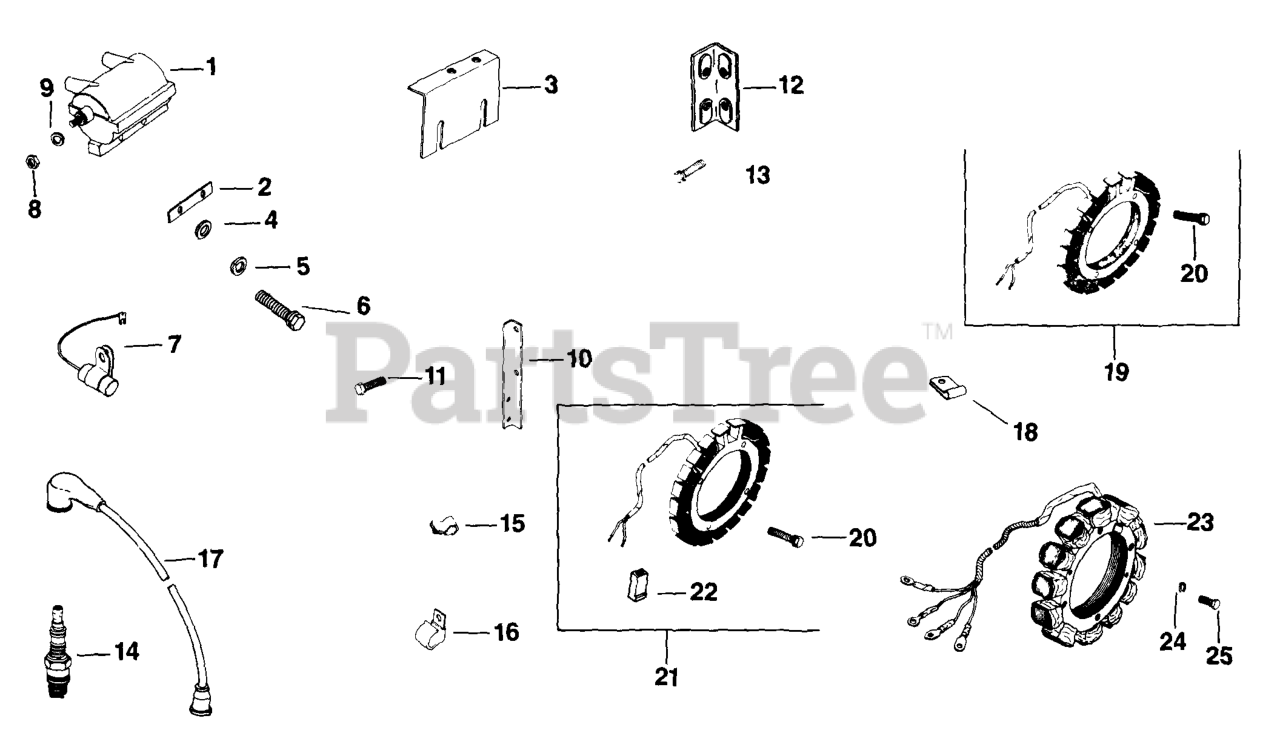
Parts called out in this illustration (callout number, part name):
1	KIT, COIL
2	PLATE, COIL MOUNTING - DISC.
4	WASHER, FLAT 1/4" (O.D. 1/2")
5	WASHER, SPRING LOCK 1/4"
6	SCREW, CAP HD 1/4-20x1-1/2" - DISCONTINUED
7	CONDENSER
8	NUT, MACH SCREW #10-32 GRD 2 USE 25 100 18-S
9	WASHER, SPRING LOCK #10
14	SPARK PLUG USE 25 132 10-S
19	KIT, 15 / 20 AMP STATOR
20	SCREW, WSH HD TAP #10-24X3/4" USE 25 086 97-S
